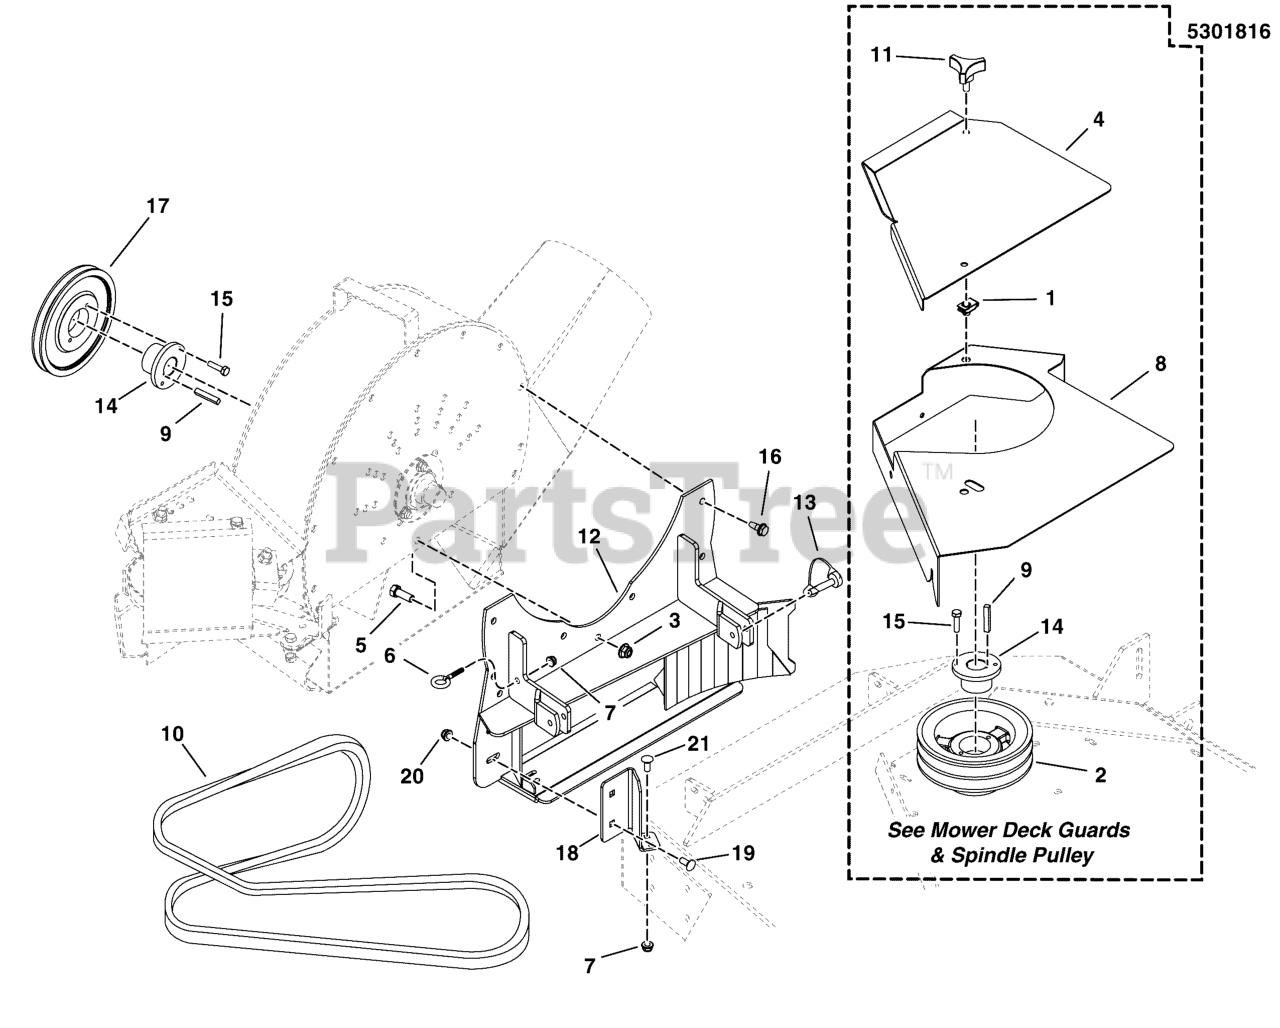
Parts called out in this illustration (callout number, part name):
1	BODY CLIP, 5/16-18-7GA MATERIAL
2	SEE MOWER DECK GUARDS & SPINDLE PULLEYS
3	NUT, 3/8-16 HEX NYLOCK FLANGE
4	SEE MOWER DECK GUARDS & SPINDLE PULLEYS
5	BOLT, 3/8-16 X 1" GD5 CZ
6	EYE BOLT, 1/4-20 X 2.5, 1THRD, .5EYE,CZ
7	NUT, 1/4-20 HEX NYLOCK FLANGE
8	SEE MOWER DECK GUARDS & SPINDLE PULLEYS
9	KEY 1/4 SQ X 1 1/2 LONG
10	BELT, 4L-SEC, 103.0EL, ARAMID, WRPD
11	KNOB, PLASTIC, 5/16-18 X 3/4
12	WELD, BLOWER MOUNT, 61 - BLK
13	SNAPPERPIN, 5/16 X 2
14	BUSHING, TAPERED HUB
15	BOLT, 1/4-20 X 1" GD5 CZ
16	BOLT, 5/16-18 X 5/8" Self Lock
17	PULLEY, BK-62H
18	BRACKET,DEFLECTOR PLATE, 61
19	BOLT, 5/16-18 X 3/4, CARRIAGE
20	NUT, 5/16-18 HEX NYLOCK FLANGE
21	BOLT-RD HD SH SQ NK 1/4-20X0. 625 G5 BLK
